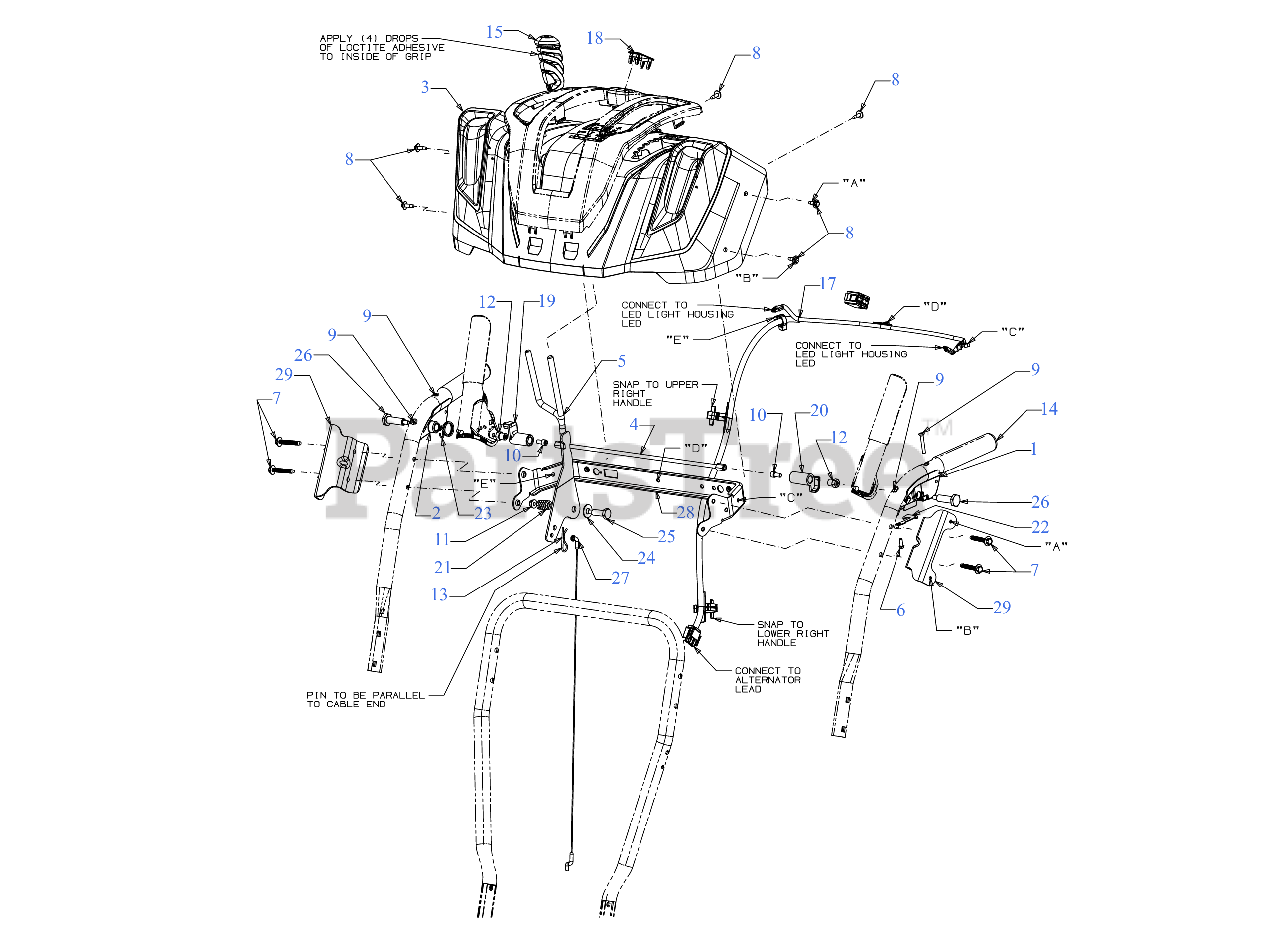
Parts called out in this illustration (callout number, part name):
1	CLUTCH LOCK HANDLE ASSEMBLY (LH)
2	CLUTCH LOCK HANDLE ASSEMBLY (RH)
3	HANDLE PANEL ASSEMBLY
5	SPEED SHIFT CONTROL (POWDER BLACK)
6	SCREW #8-16 x .50
7	SCREW 1/4-20 x 1.625
8	SCREW M6-1 x .625
9	SCREW #10-24 x 1.375
10	SCREW 1/4-20 x .50
11	FLANGE LOCK NUT
12	HEX NUT W/PATCH
13	INTERNAL COTTER PIN
15	PTO HANDLE GRIP .355 ID
17	2 HEADLIGHT HARNESS
18	PANEL SWITCH PLUG
20	CLUTCH LOCK CAM
21	COMPRESSION SPRING
22	CLUTCH SPRING
23	TORSION SPRING
24	FLAT WASHER .40X.88X.060
25	SHOULDER SCREW
26	SHOULDER SCREW .437 x 1.345 1/4-20
27	SPEED SELECTOR CABLE (PLASTIC)
28	HANDLE SUPPORT BRACKET (POWDER BLACK)
29	HANDLE PANEL BRACKET (POWDER BLACK)
